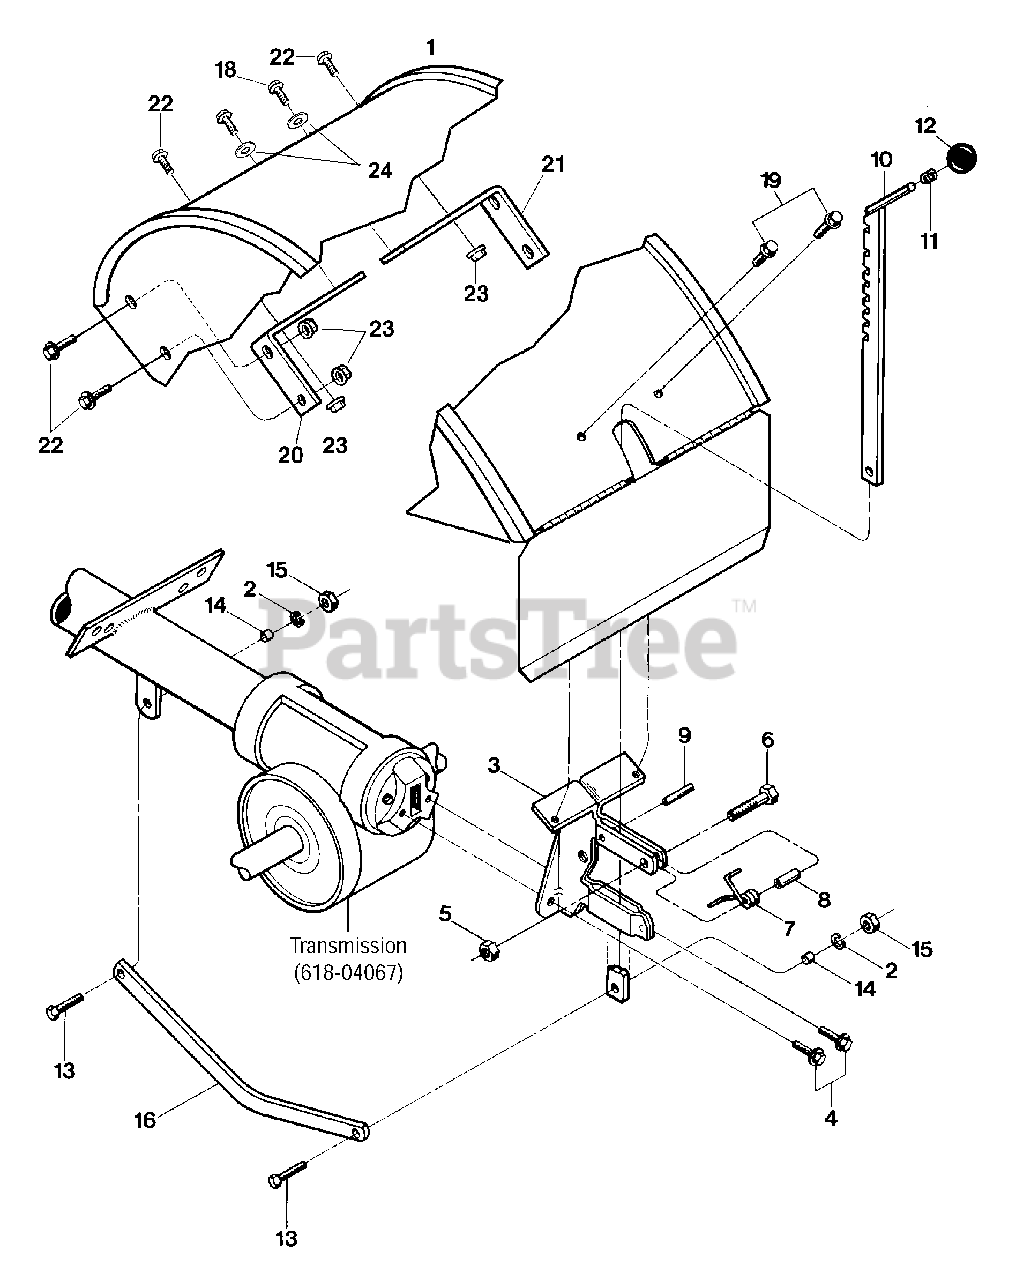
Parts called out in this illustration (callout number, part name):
1	Hood, Tine
2	Lockwasher, 3/8
3	Bracket, Hood & Depth Regulator
4	Hex Hd. Flg. Screw, 5/16-18 x 5/8
5	Hex Lock Nut, 1/4-20
6	Hex Hd. Screw, 1/4-20 x 1
7	Spring, Depth Regulator Plunger
9	Roll Pin (spiral), 1/4 x 1
10	Bar Assembly, Depth Adjustment
11	Retaining Ring (Tolerance Ring)
12	Knob, Depth Regulator
13	Hex Hd. Screw, 3/8-16 x 1-1/4
14	Bushing (spacer)
15	Hex Nut, 3/8-16
16	Drag Bar, Depth Regulator
18	Hex Hd. Screw, self-tapping,16-18 x 7/8
19	Flange Screw, self-tapping,1/4-20 x 1/2
20	Support Bracket, Left-Side
21	Support Bracket, Right-Side
22	Hex Hd. Screw, 5/16-18 x 5/8
23	Hex Nut, 5/16-18
24	Bell Washer
618-04067	Transmission
